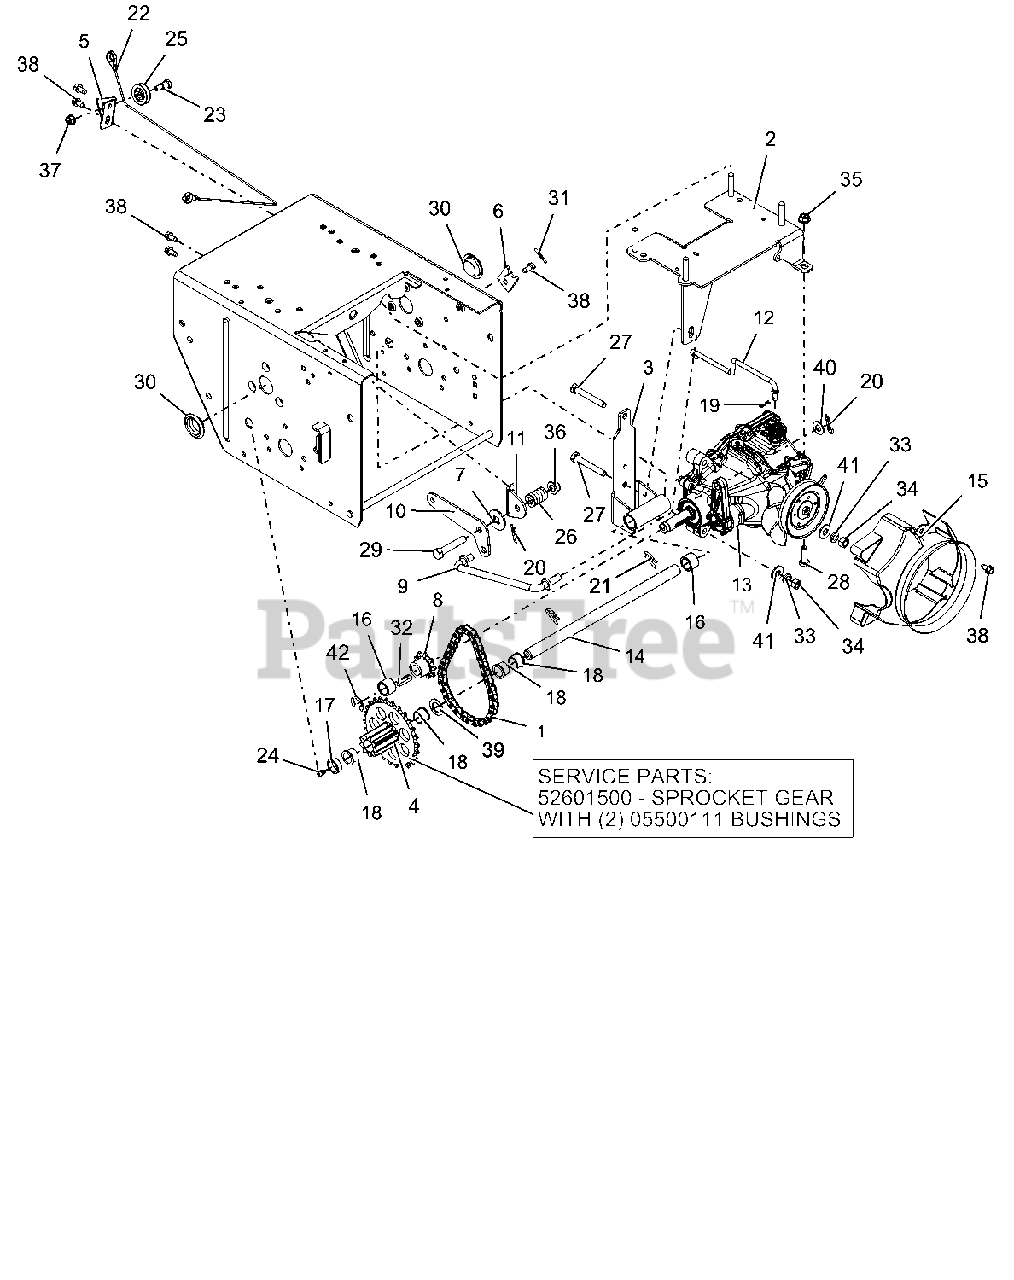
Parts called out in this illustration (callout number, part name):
1	CHAIN - #41, 32 PITCHES
2	BRACKET, HYDROSTATIC TRANS XLG
3	TRANS MOUNT, TENSIONING, WHEEL
4	BSHG-FLG .625X.750X.500X.875
4	PINION & SPROCKET
4	PINION & SPROCKET W/BUSHINGS
5	BRACKET, CABLE PULLEY
6	TAB, ANTI ROTATION
7	FRICTION WASHER
8	SPROCKET, PINION 9T W/KEY
9	ROD, HYDRO TRANS SHIFT
10	PIVOT, HYDRO TRANS SHIFT
11	BRACKET, HYDRO SHIFT PIVOT
12	ROD, HYDRO BYPASS
13	TRANSMISSION, HYDROSTATIC
14	SHAFT, PINION - HARDENED
15	SHROUD, HYDROGEAR RT-310
16	SPACER, .635X.880X.611
17	BSHG-SLV, .635X.880X.305
18	BSHG-FLG .625X.750X.500X.875
19	PIN-HAIR INT .06X.18X.77
20	PIN-HAIR INT .08X.18X1.18 YWZC
21	PIN, SPRING CLIP
22	CABLE, TRACTION, HYDRO PRO
23	BOLT, SHLDR-.375X.375X.25-20
24	ZERK,FITTING .25X.125 DRIVE IN
25	PULLEY, CABLE
26	SG-COMP .187X.56X1.62
27	@BLT-HEX .31-18X2.25 GR5 YWZC
28	@BLT-HEX .31-18X1.00 GR5 YWZC
29	@BLT-HEX .38-16X2.00 GR5 YWZC
30	PLUG, HOLE - 1.125"
31	@PIN-GRV .125X1.00 TP E ALLOY
32	KEY-SQ .188X1.0X.188 SAE 8630
33	WSHR-LK .312X.097 HVY YWZC
34	@NUT-HEX .31-18 YWZC
35	@NUT-LK-TOP-FLG .31-18 YWZC
36	@NUT-LK-TOP-FLG .38-16 YWZC
37	@NUT-LK-TOP-FLG .25-20 YWZC
38	SCR-TAP .25-20X.50 HWH TR YWZ
39	WSHR-FL-STL .630X1.005X.062 YZ
40	@WSHR-FL-STL.406X.812X.065 YWZ
41	@WSHR-FL-STL.38X.875X.083 YWZC
42	RG-RTNG-EXT .625X.042
